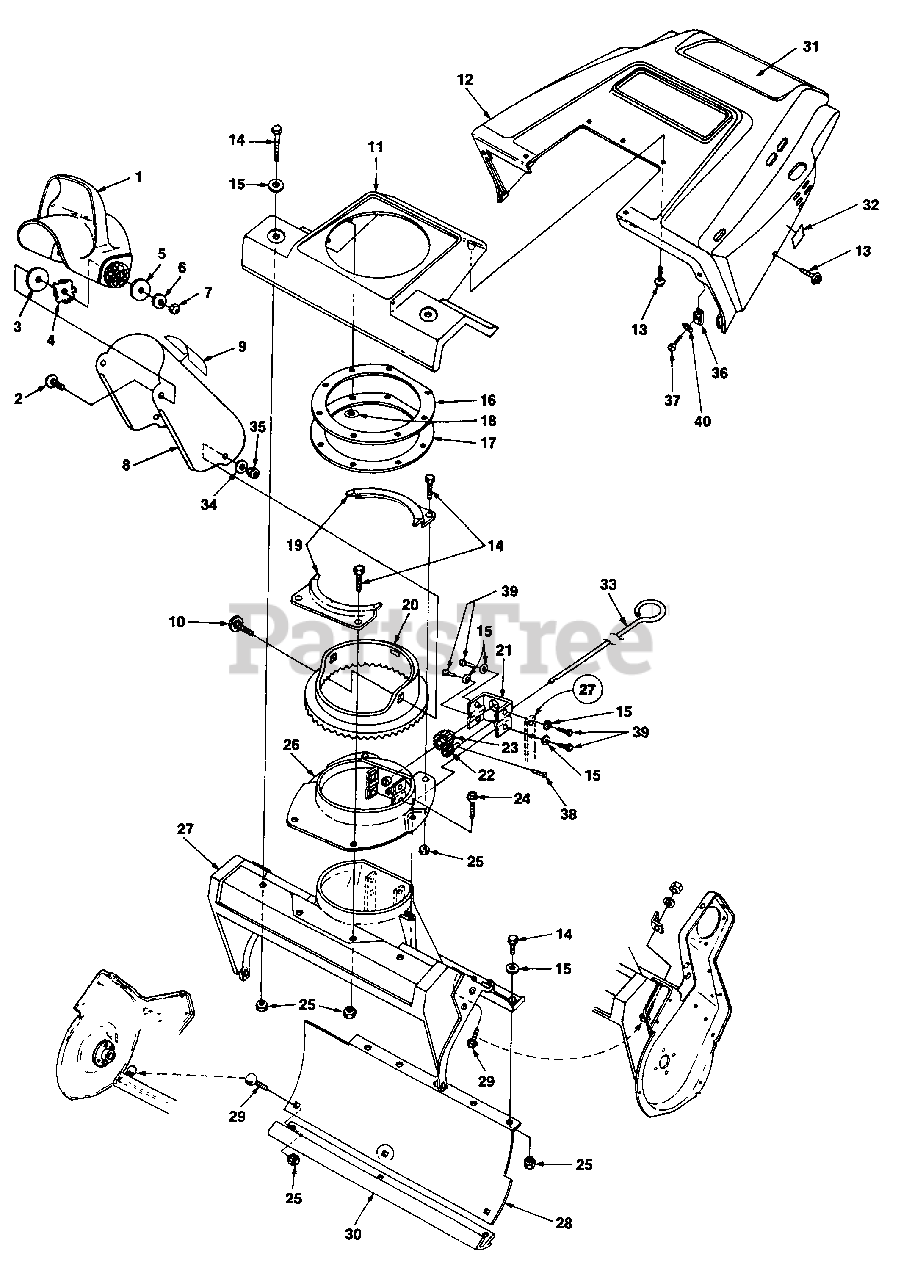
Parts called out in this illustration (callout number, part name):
1	DEFLECTOR
2	BOLT- Carr. 5/16-18 x 1
3	WASHER- Flat rubber
4	WASHER- Octagon
5	WASHER- Flat
6	WASHER- Belleville
7	NUT- Flange 5/16-18
8	CHUTE
9	DECAL- Warning
10	BOLT- Square neck 5/16-18 x 5/8
11	COWLING- Transition
12	COWLING- Upper
13	SCREW- Thd. forming #10 x 5/8
14	SCREW- Hex 1/4-20 x 3/4
15	WASHER- Plain 1/4
16	GASKET- Chute
17	RETAINER- Gasket
18	NUT- Push on
20	BASE- Chute
21	BRACKET- Gear
22	DRIVE- Gear
23	GEAR- Idler
24	SCREW- Plastite
25	NUT- Flange 1/4-20
26	PLATE- Chute base
27	HOUSING- Auger
29	BOLT- 1/4 x 3/4
31	DECAL- Console
32	DECAL- Warning
33	ROD- Crank adj.
34	WASHER- Lock 5/16
35	NUT- Hex 5/16-18
36	NUT- Speed
37	SCREW- 1O x 1 1/2
38	PIN- Cotter 1/8 dia.
39	SCREW- Hex hd.
40	WASHER- Flat
